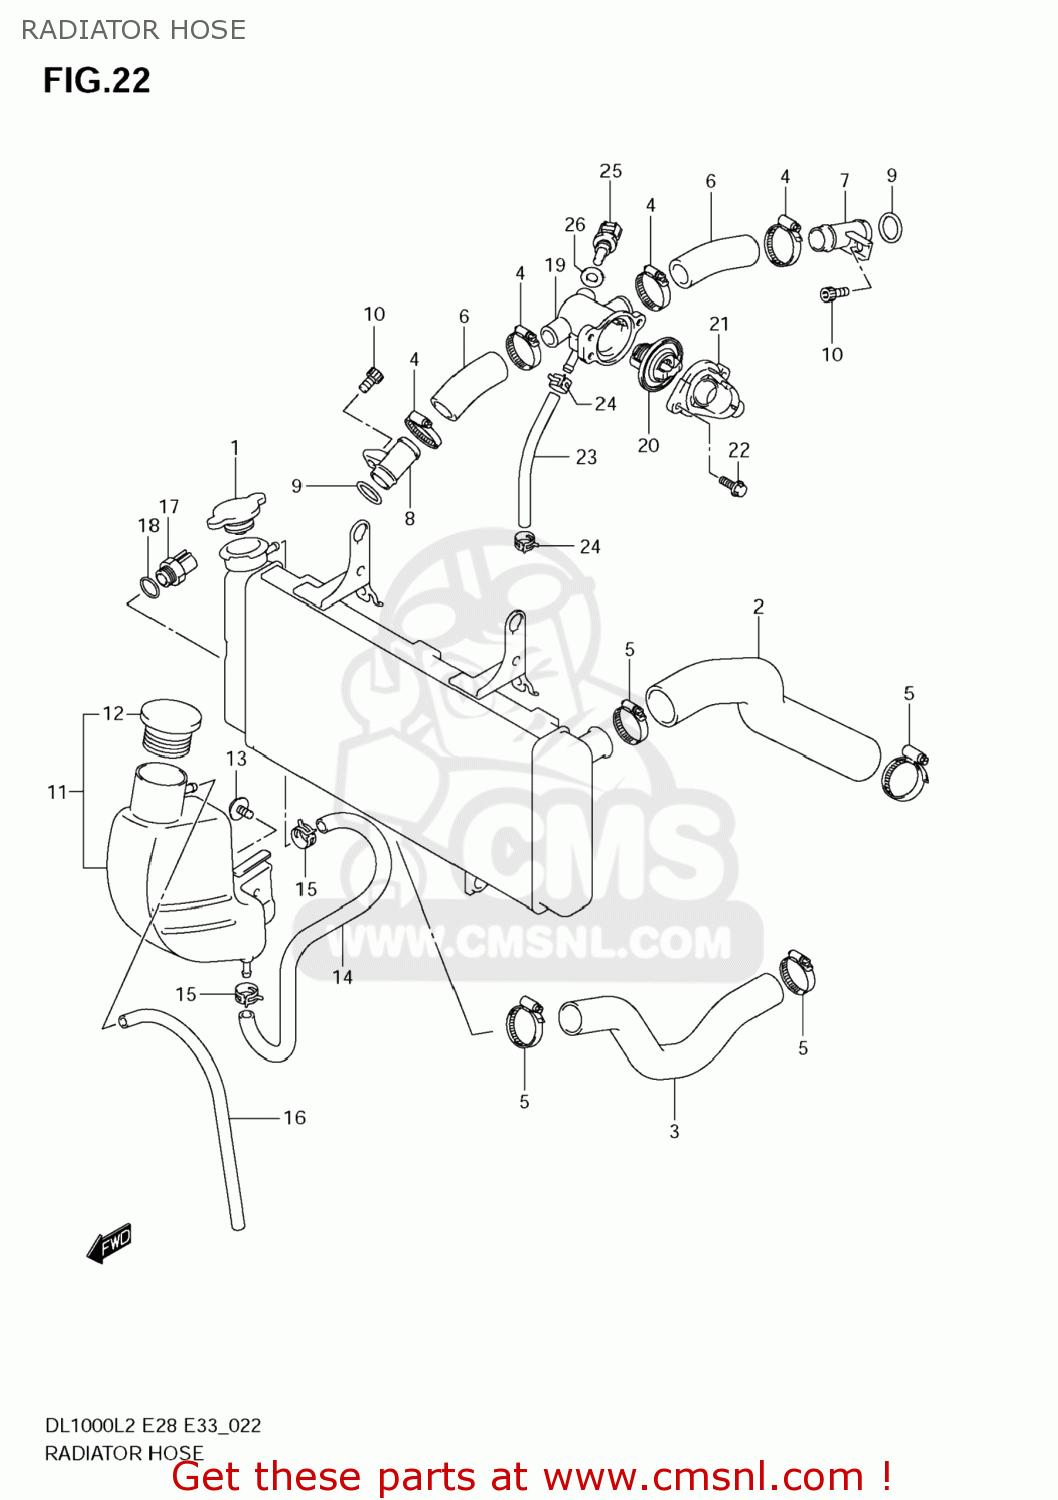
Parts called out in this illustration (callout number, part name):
1	CAP,RADIATOR
2	HOSE,RADIATOR INLET
3	HOSE,RADIATOR OUTLET
4	CLAMP
5	CLAMP
6	HOSE,CONNECTOR INLET
7	UNION,CONNECTOR HOSE
8	UNION,CONNECTOR HOSE
9	O RING(D:3.2,ID:17.8)
10	BOLT
11	TANK ASSY,RESERVOIR
12	CAP,WATER RESERVOIR TANK
13	BOLT(6X12)
14	HOSE,RESERVOIR TANK INLET
15	CLIP
16	HOSE(5X9X2000)
17	SWITCH,RADIATOR FAN
18	O-RING
19	CONNECTOR,THERMOSTAT INLET
20	THERMOSTAT,WATER
21	CAP,THERMOSTAT CONNECTOR
22	BOLT
23	HOSE,WATER BYPASS
24	CLAMP
25	SENSOR,WATER TEMP
26	GASKET(12X17X1) (NAS)
